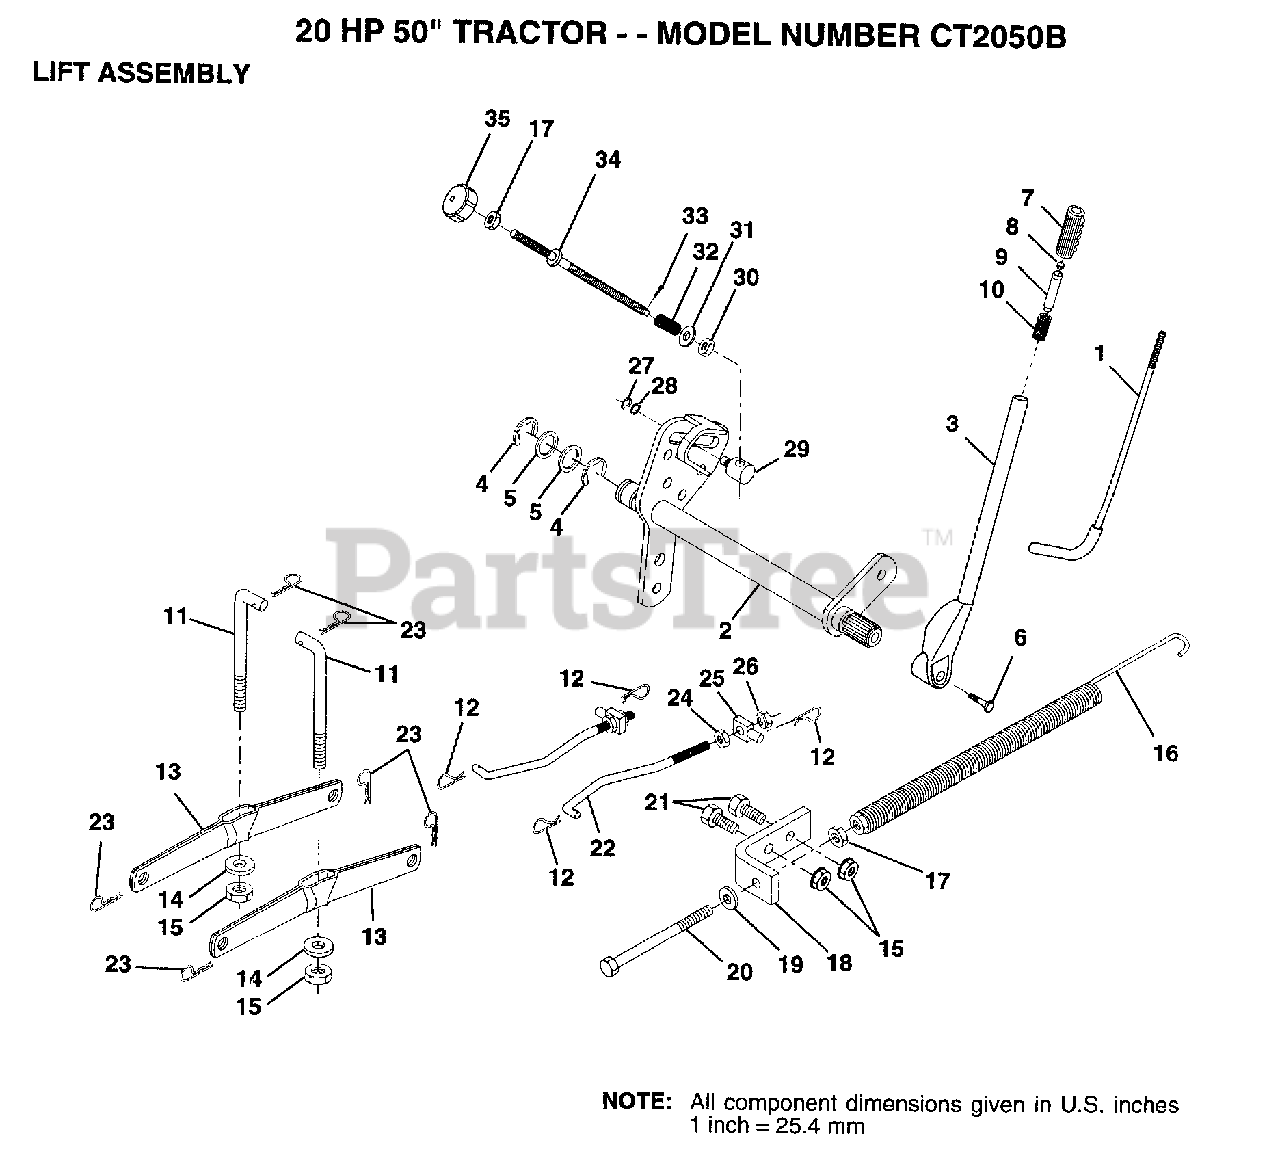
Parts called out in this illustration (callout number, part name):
1	LEVER ROD LT
4	E-RING
5	WASHER
6	"BOLT,HEX"
7	GRIP
8	BUTTON PLUNGER YELLOW
10	SPRING T
12	RETAINER.SPRING
14	BEARING PVT LH
15	NUT
17	NUT
18	BRACKET SPRING AS
19	WASHER
20	BOLT-ADJ SPRING T
21	BOLT
22	LINK.FRONT
24	NUT
25	TRUNION
26	NUT.LK.W/WSH.1/2.
27	KLIP RING
28	WASHER
29	TRUNION LT
30	NUT T
31	WASHER
32	SPRING.COMP.INF.H
34	ROD.ADJ.LIFT
35	KNOB INF 3/8-16
